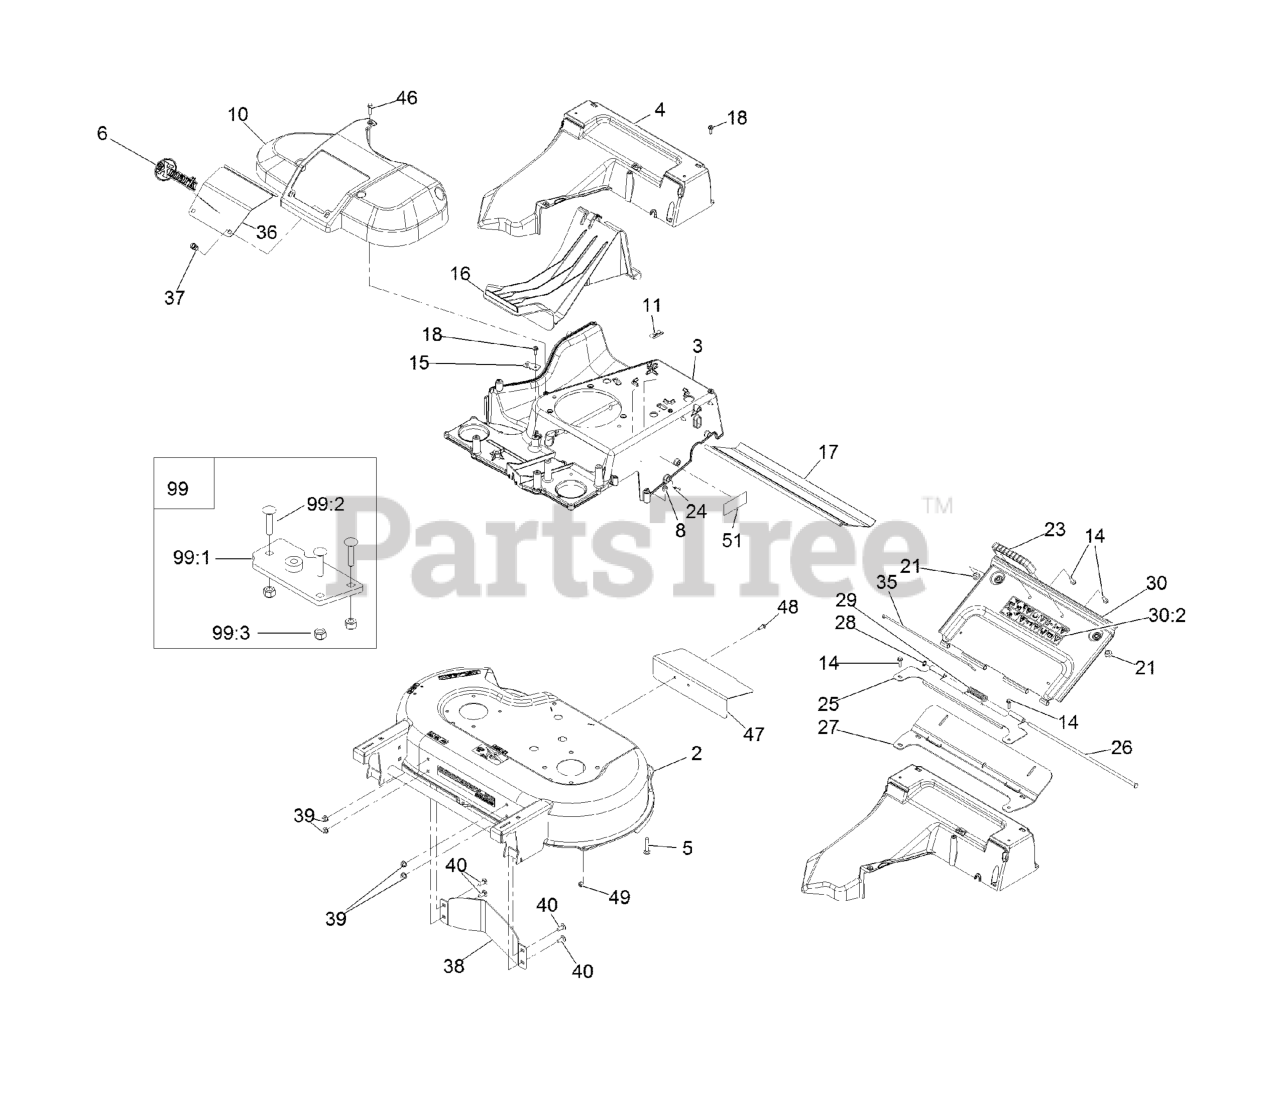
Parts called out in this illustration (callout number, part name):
2	DECK-30, W/DECALS
3	FRAME
5	BOLT-CAR
6	DECAL-EXMARK LOGO
8	NUT-LOCK, NI
10	COVER-BELT
11	Decal-Patent Ttco.Com
14	SCREW-HWH
15	BRACKET-CABLE, TRACTION
16	PLUG-MULCH
17	SHIELD-TRAILING
18	SCREW-HWHTF
23	HANDLE-DOOR
24	SCREW-PTH
25	BRACKET-HINGE
26	PIN-HINGE
27	SEAL-DOOR
28	RING-RETAINING
29	SPRING-TORSION, COVER
30	REAR DOOR ASM
30:2	DECAL-WARNING
35	CLIP-SEAL
36	DOOR-ACCESS
37	FASTENER
38	BAFFLE-CONTROL
39	NUT-HF, NI
40	SCREW-HSBH
46	SCREW-HWHTF
47	DEFLECTOR-REAR
48	SCREW-HWH
49	NUT-LOCK, NI
51	DECAL-ARRESTOR, SPARK
99	FRAME PLATE KIT
